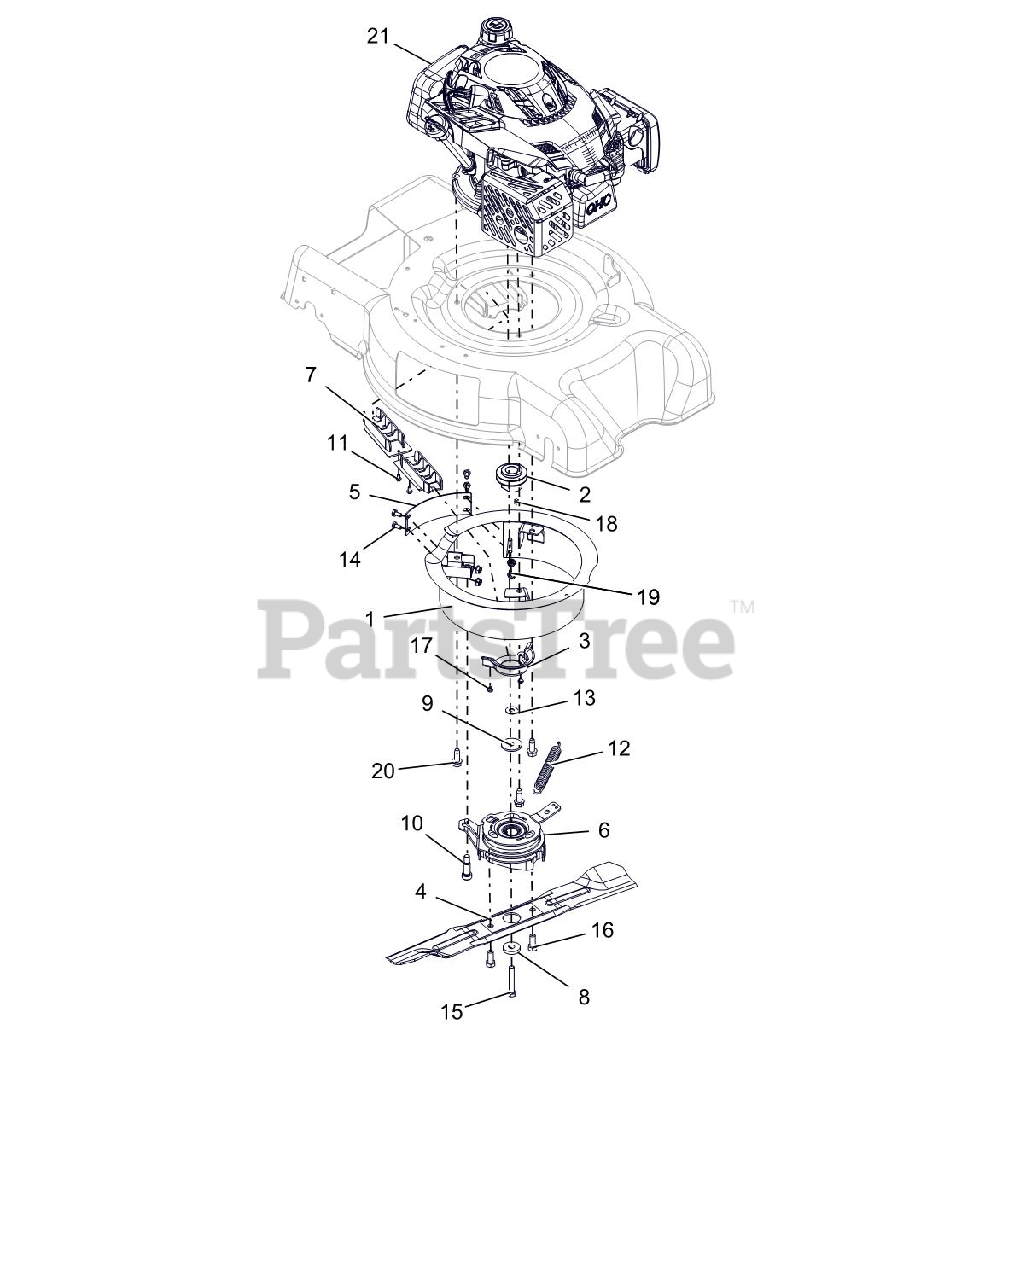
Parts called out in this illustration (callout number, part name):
1	WLDMT, ENCLOSURE - BBC
2	PULLEY, 7/8 MACHINED LM DRIVE
3	GUIDE, BELT CRANK
4	BLADE, MOWER 21" HIGH LIFT-BBC
5	BAFFLE, BBC
6	CLUTCH, RAZOR/XD3, 7/8"
7	GUIDE, BELT INNER
8	WSHR-FL-STL .44X1.25X.25 YWZC
9	WSHR-FL-STL .380X1.50X.125YWZC
10	BLT,SHLDR 12MM X 25 W/ M10 THD
11	SCR-TAP 10-24X.375 PRE-COAT 80
12	SPRING, EXTENSION BBC
13	WSHR-HDND .375X.875X.064 YWZC
14	@BLT-HEX .25-20X.50 GR5 YWZC
15	BLT-HEX 3/8-24 X2.25 GR8
16	BLT-HEX M10 X 1.5X25 YWZC
17	SCR-TAP 10-24X.25 CRSLPH TR YZ
18	KEY-SQ .188X.188X.375
19	@NUT-LK-TOP-FLG .25-20 YWZC
20	@SCR-TAP .38-16X1.00 HWH TR YZ
21	ENGINE, SUBARU 175CC VERT. BBC
